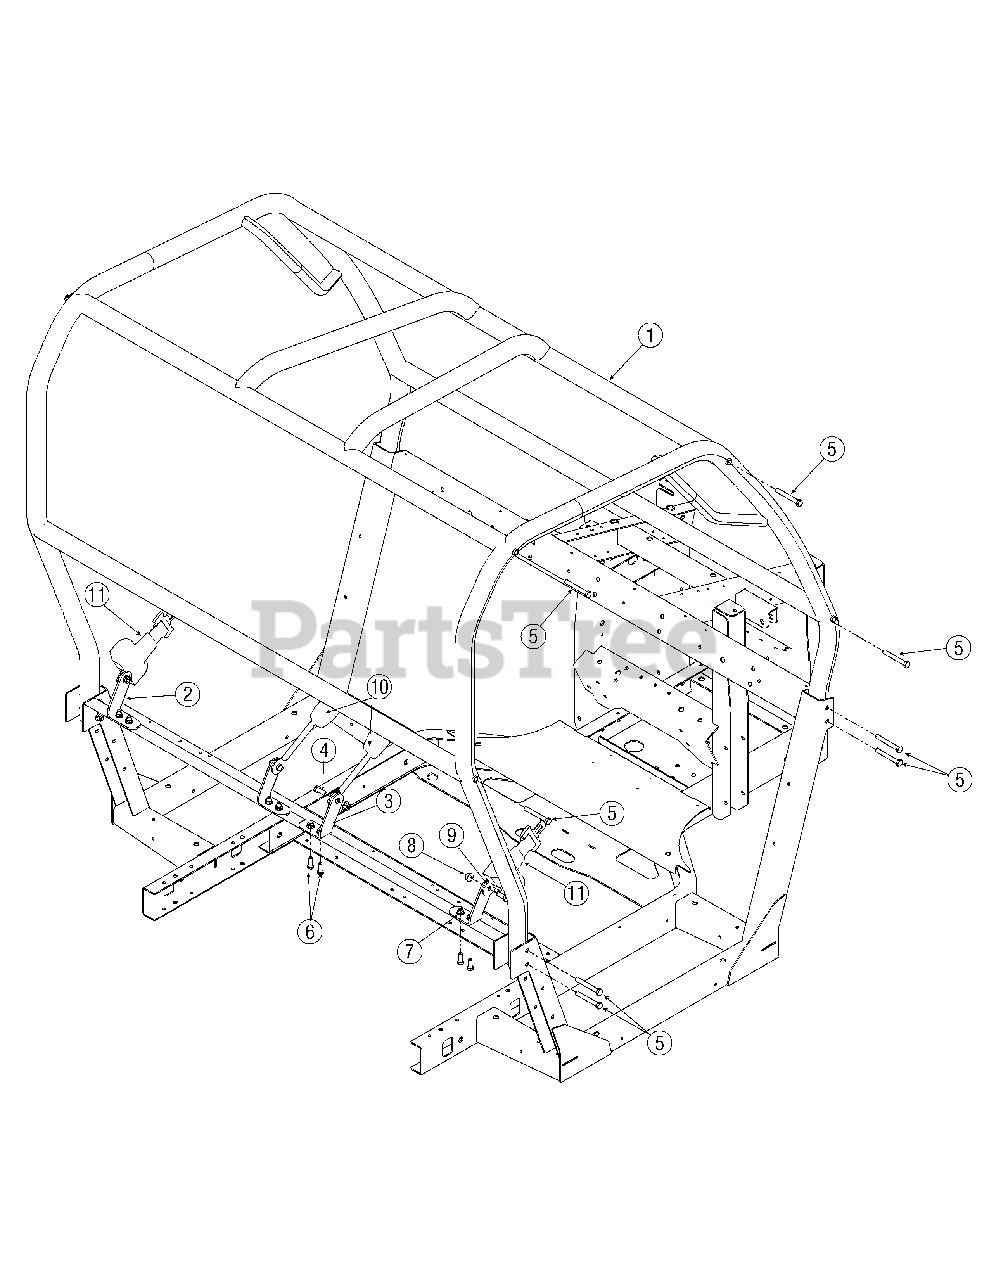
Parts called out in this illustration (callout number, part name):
1	Frm Assembly, OPS, UV
4	Screw, 3/8-16 x 1.00
5	Screw, 3/8-16 x 2.75
6	Scew, 5/16-18 x .875
7	Nut, Flglk, 5/16-18
8	Nut, Flglk, 3/8-16
9	Wash, Flat, .406 x 1.5 x .105
10	Belt, Seat
11	Belt, Seat
